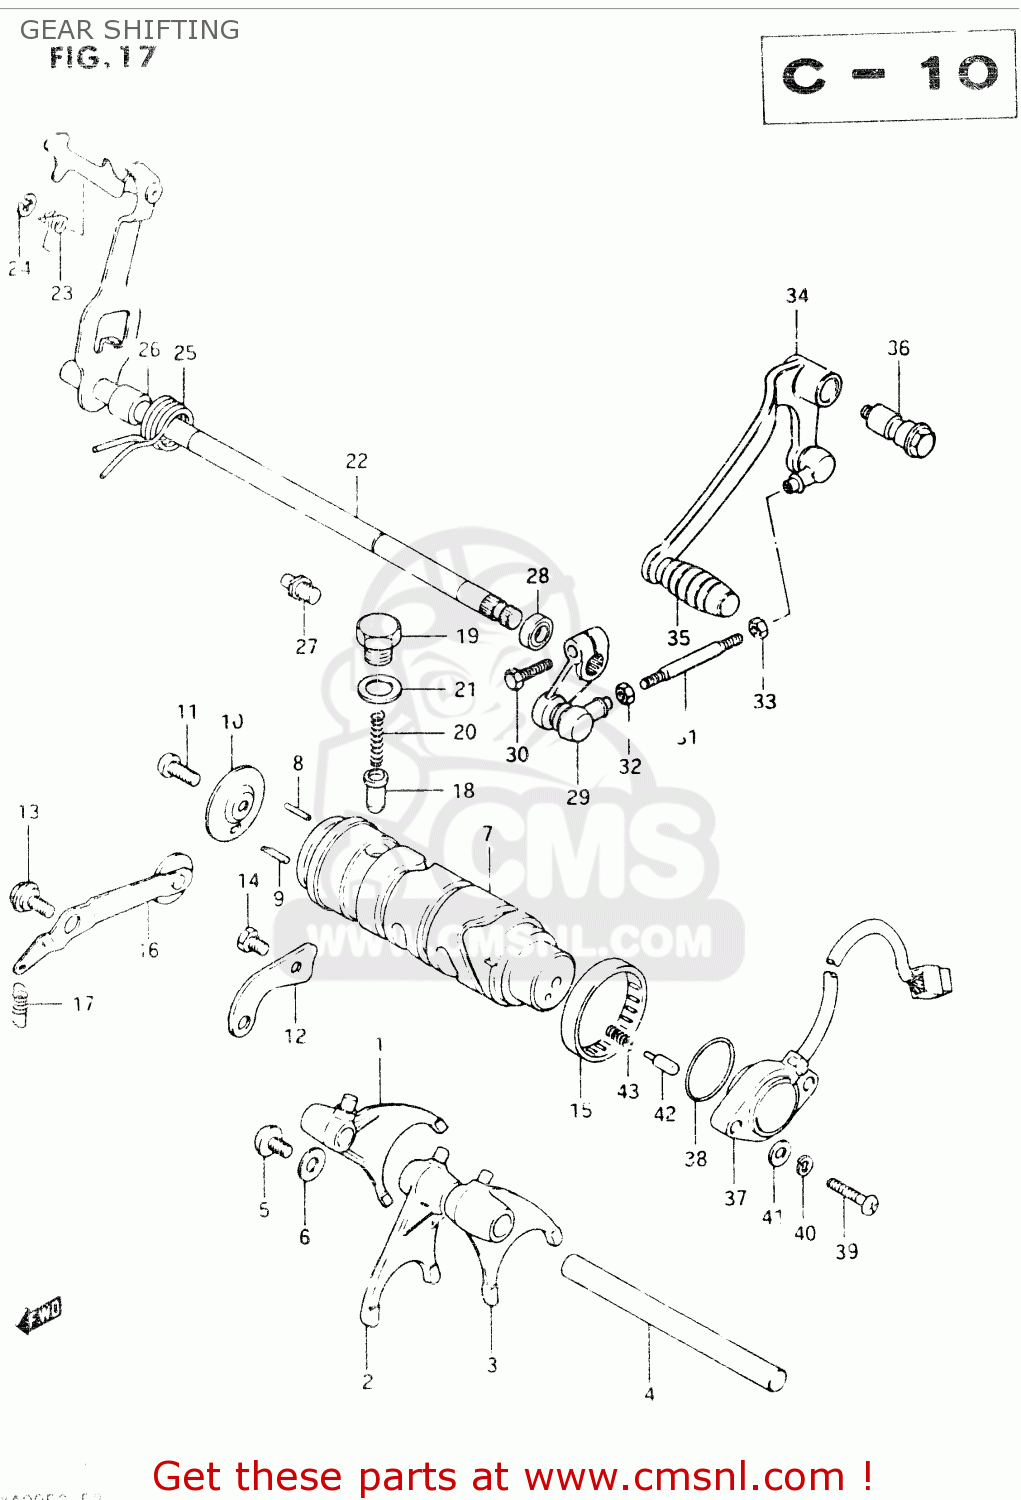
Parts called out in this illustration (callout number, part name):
1	FORK,GEAR SHIFT NO.1
2	FORK,GEAR SHIFT NO.2
3	FORK,GEAR SHIFT NO.2
4	SHAFT,GEAR SHIFT FORK
5	SCREW
6	WASHER
7	CAM,GEAR SHIFT
8	PIN(4X18.5)
9	PIN
10	RETAINER,GEAR SHIFT CAM DR PIN
11	SCREW
12	GUIDE,GEAR SHIFT CAM
13	BOLT
14	BOLT, UPPER
15	BEARING(40X47X12)
16	STOPPER,GEAR SHIFT CAM NO.1
17	SPRING
18	STOPPER,GEAR SHIFT CAM NO.2
19	HOLDER,GEAR SHIFT CAM STOP SPR
20	SPRING
21	GASKET(14X19.2X2) (NAS)
22	SHAFT,GEAR SHIFT
23	SPRING
24	E RING
25	SPRING
26	SPACER(12X20X15.3)
27	STOPPER,GEAR SHIFT CAM
28	OIL SEAL
29	ARM,GEAR SHIFT LINK
30	BOLT
31	ROD,GEAR SHIFT LINK
32	NUT
33	NUT
34	LEVER ASSY,GEAR SHIFT
35	RUBBER,GEAR SHIFT PEDAL
36	SHAFT,GEAR SHIFT LEVER
37	BASE ASSEMBLY,NEUTRAL SWITCH TERMINAL
38	O-RING (D:2.4 ID:26.2)
39	SCREW
40	LOCK WASHER
41	WASHER
42	PIN(5X15.5)
43	SPRING
